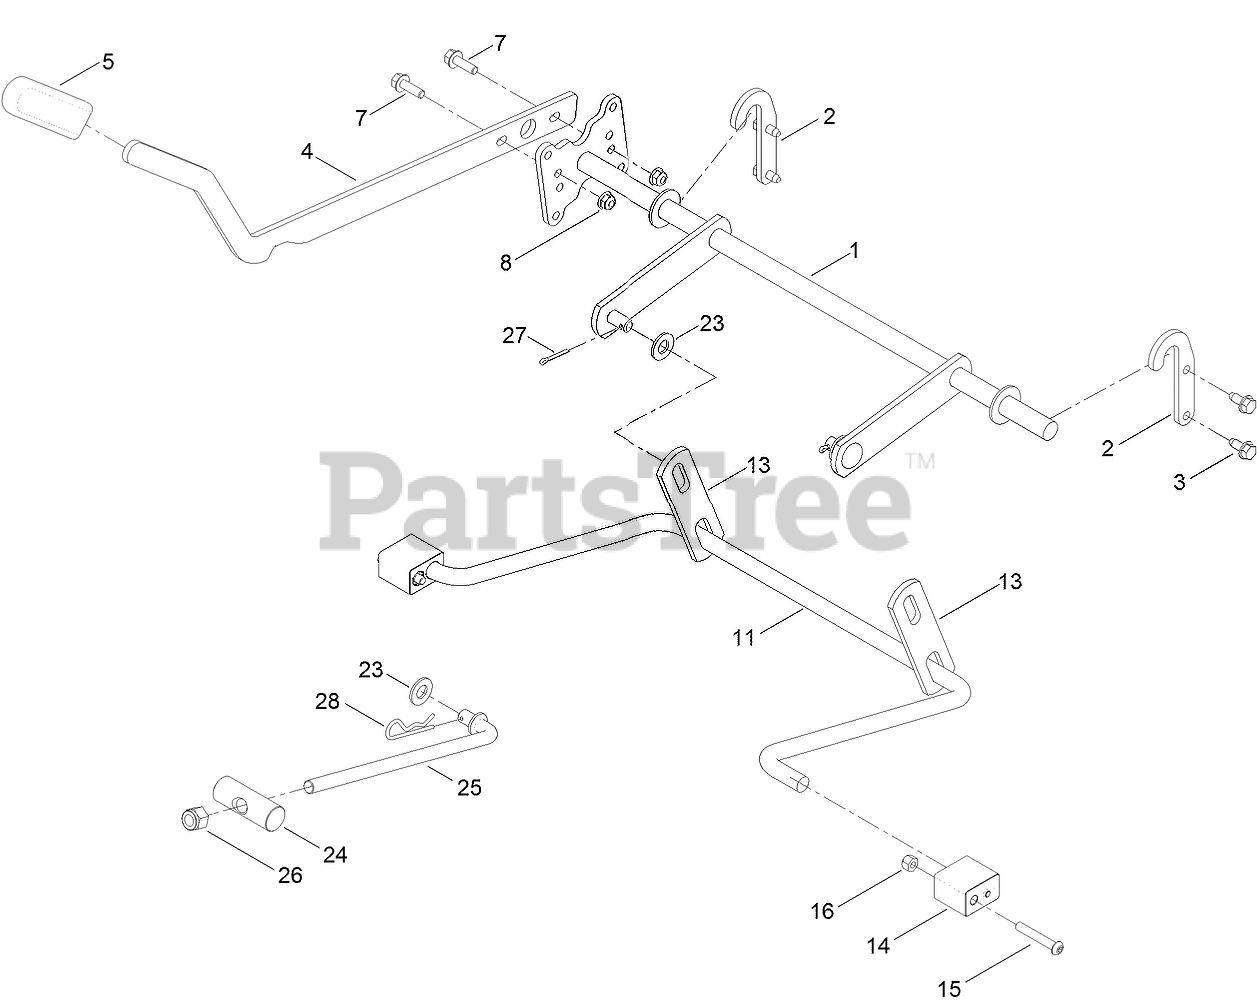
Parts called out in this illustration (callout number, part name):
1	LIFT-DECK, NARROW
2	BRACKET-LIFT
3	SCREW-HWHTF
4	LEVER-LIFT
5	GRIP-LEVER
7	SCREW-HHF
8	NUT-HF, NI
11	ARM-LIFT, REAR
13	LINK-LIFT
14	BLOCK-PIVOT
15	SCREW-HSBH
16	NUT-LOCK, NI
23	WASHER-FLAT
24	PIN-PIVOT
25	ROD-MOUNT, DECK
26	NUT-HEX
27	PIN-COTTER
28	PIN-COTTER
